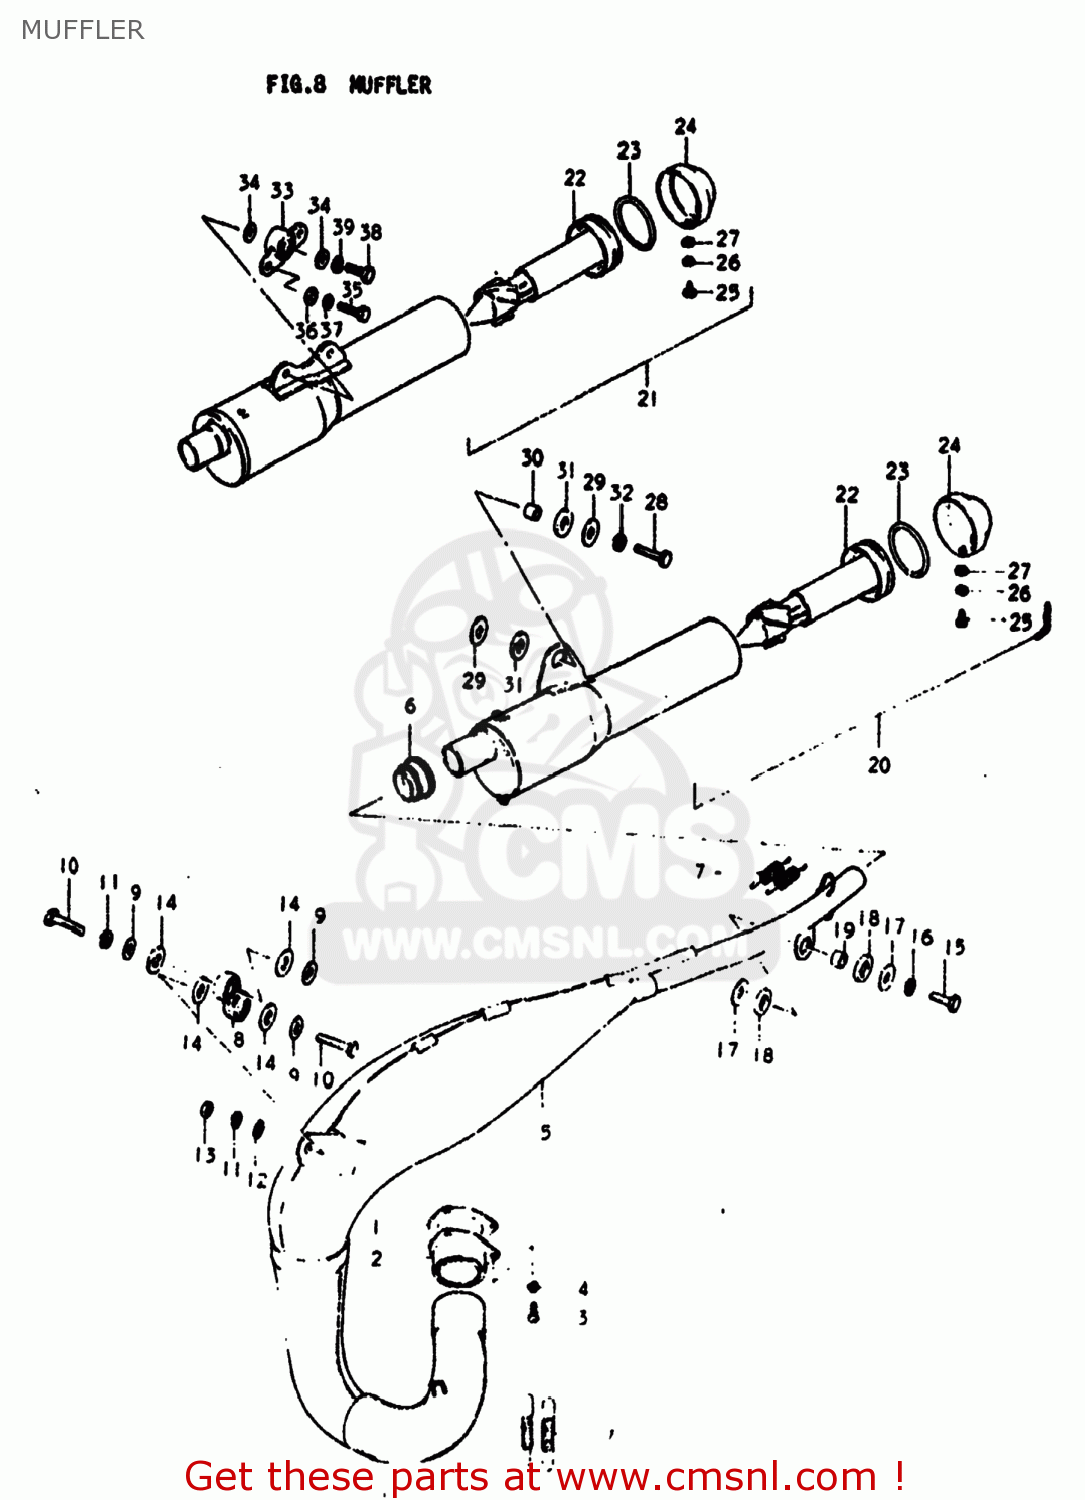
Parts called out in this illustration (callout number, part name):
1	GASKET,EXHAUST PIPE (MCA)
2	FLANGE,EXHAUST PIPE
3	SCREW
4	LOCK WASHER
5	BODY,MUFFLER
6	CONNECTOR,MUFFLER
7	SPRING
8	DAMPER,MUFFLER
9	WASHER
10	BOLT
11	LOCK WASHER
12	WASHER
13	NUT
14	WASHER(13X28X1.6)
15	BOLT(8X27)
16	LOCK WASHER
17	WASHER (8.5X29X1.6)
18	CUSHION
19	SPACER (8.6X13.8X13)
20	MUFFLER ASSEMBLY,SECOND
21	MUFFLER ASSEMBLY
22	TUBE,MUFFLER CLEAN OUT
23	O-RING (D:3.5 ID:54.4)
24	COVER,SECOND MUFFLER TAIL
25	SCREW(6X8)
26	LOCK WASHER
27	WASHER
28	BOLT (8X30)
29	WASHER (8.5X29X1.6)
30	SPACER (8.6X13.8X13)
31	CUSHION
32	LOCK WASHER
33	DAMPER,MUFFLER SUPPORT
34	WASHER (8.5X29X1.6)
35	BOLT, UPPER
36	WASHER
37	LOCK WASHER
38	BOLT 8X45
39	LOCK WASHER
